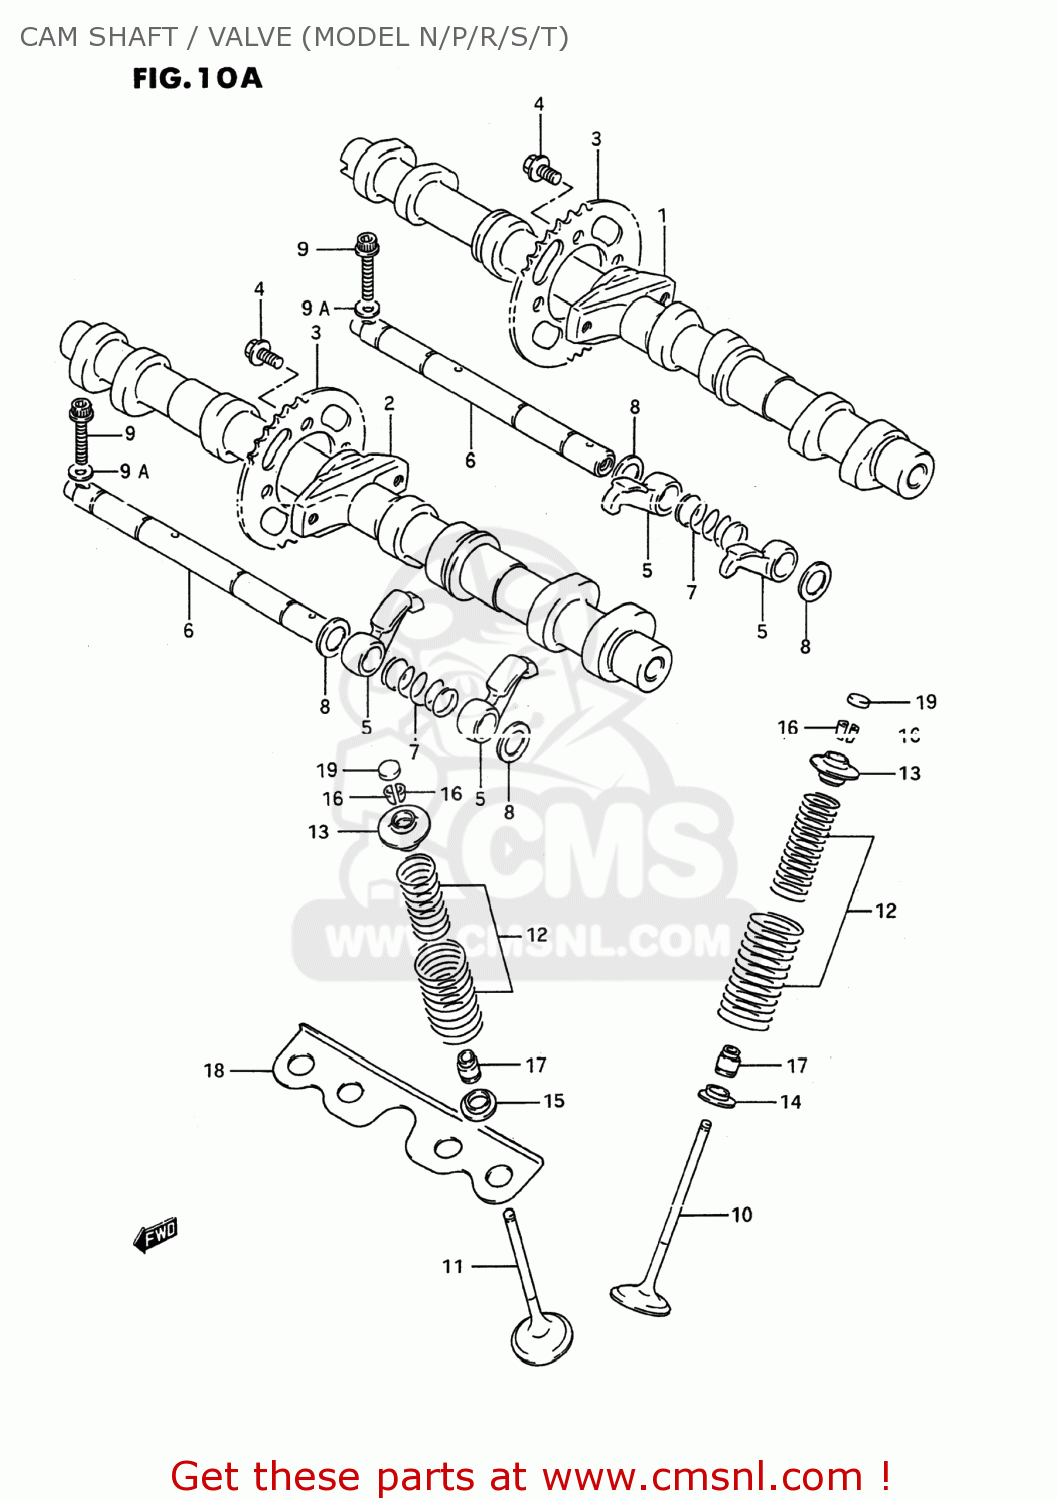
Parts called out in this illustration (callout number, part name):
1	CAMSHAFT INTAK
2	CAMSHAFT,EXHAUST
3	SPROCKET,CAMSHAFT
4	BOLT(7X11)
5	ARM,VALVE ROCKER
6	SHAFT,VALVE ROCKER ARM
7	SPRING
8	WASHER
9	BOLT
9A	WASHER
10	VALVE,INTAKE
11	VALVE,EXHAUST
12	SPRING SET,VALVE
13	RETAINER,VALVE SPRING
14	SEAT,VALVE SPRING
15	SEAT,VALVE SPRING EXH INNER
16	COTTER VALVE
17	SEAL,OIL(5X10X9.7)
18	PLATE,VALVE SEAT
19	SHIM,TAPPET(T:2.3)
20	SHIM SET,TAPPET
21	CASE,TAPPET SHIM
